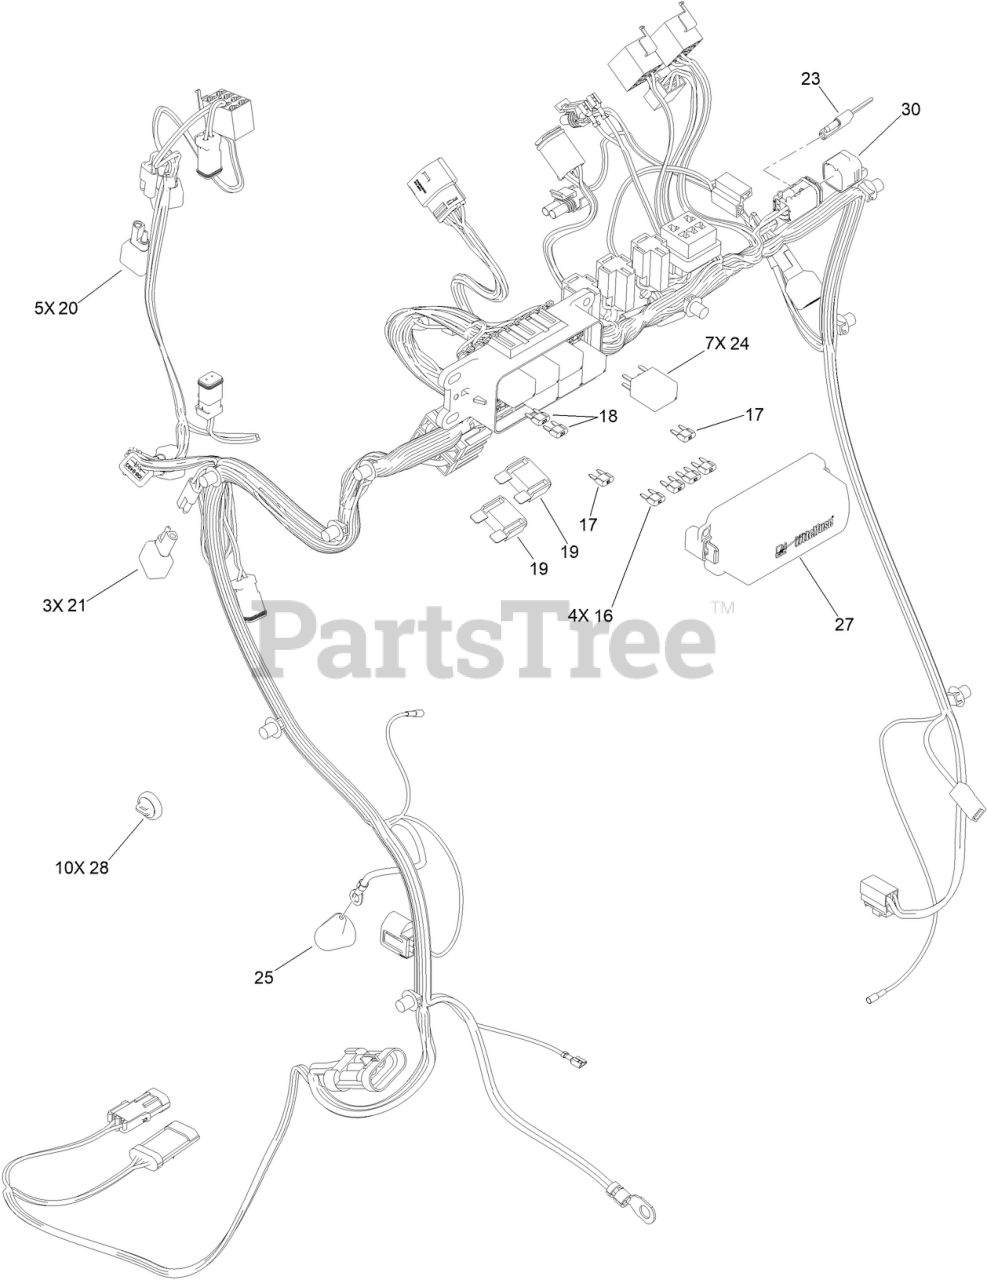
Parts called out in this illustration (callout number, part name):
16	FUSE-MINI BLADE, 10 AMP
17	FUSE-MINI BLADE, 15 AMP
18	FUSE-MINI BLADE, 20 AMP
19	FUSE-BLADE, 50 AMP
21	DIODE-TVS
23	CAP-TETHERED
24	RELAY-280 ISO
25	INSULATER-TERMINAL, BLACK
27	COVER-LITTELFUSE, PDM 60F
28	MOUNT-TIE WRAP, MAGNETIC
30	CAP-PLUG, 6 WAY
